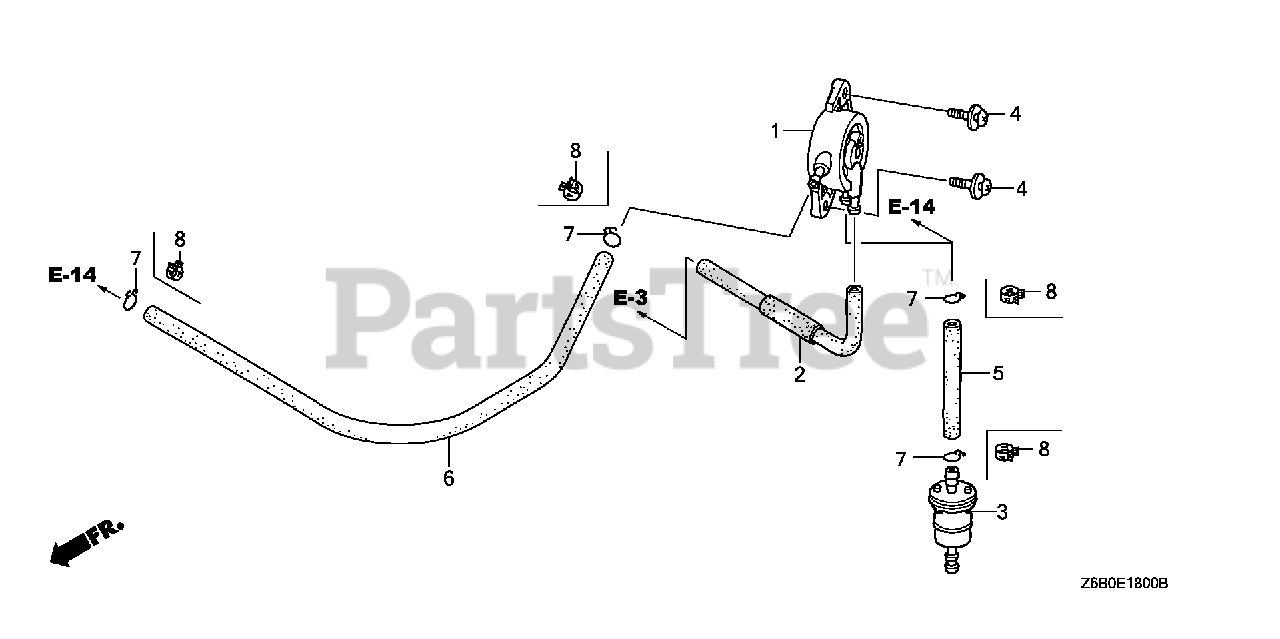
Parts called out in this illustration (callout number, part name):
3	FILTER, FUEL
5	BULK HOSE, FUEL (5.5X3000) (Honda Code 5338587). (5.5X150)
7	CLIP, TUBE (B10)
